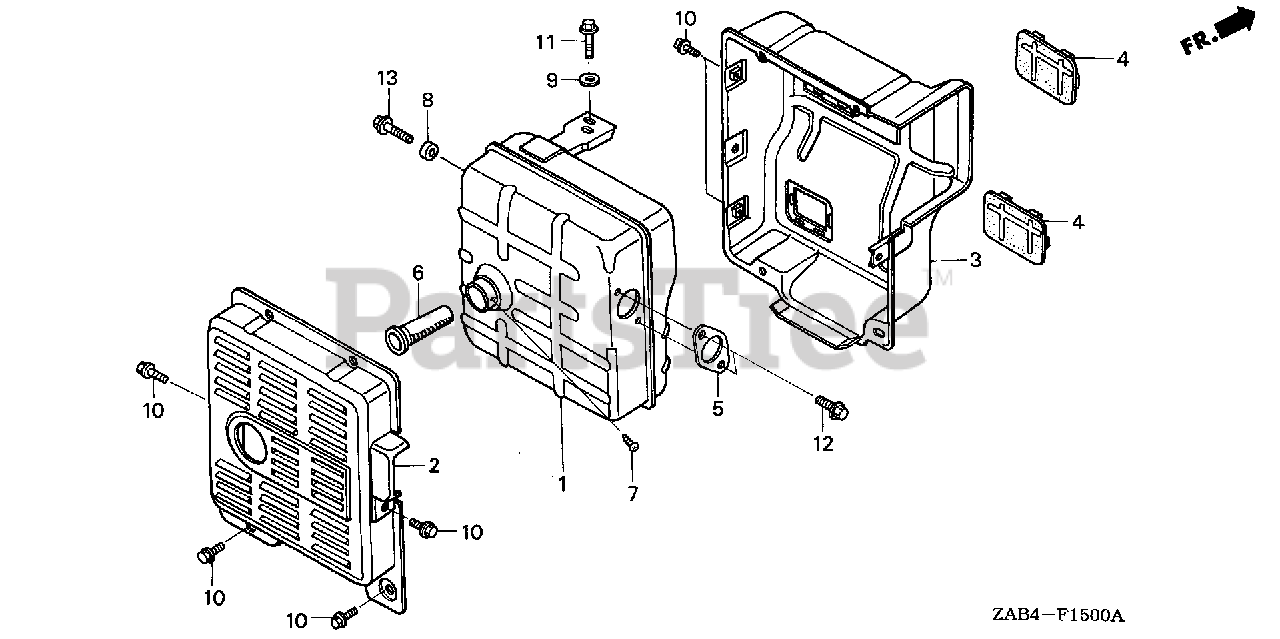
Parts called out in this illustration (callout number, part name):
1	MUFFLER
2	PROTECTOR, MUFFLER (OUTER)
3	PROTECTOR, MUFFLER (INNER)
4	SEAL, MUFFLER PROTECTOR
5	GASKET, EX. PIPE
6	ARRESTER, SPARK
7	SCREW, TAPPING (4X8)
9	WASHER, PLAIN (8MM)
10	BOLT, FLANGE (6X10)
11	BOLT, FLANGE (8X16)
12	BOLT, FLANGE (8X20)
13	BOLT, FLANGE (8X25)
